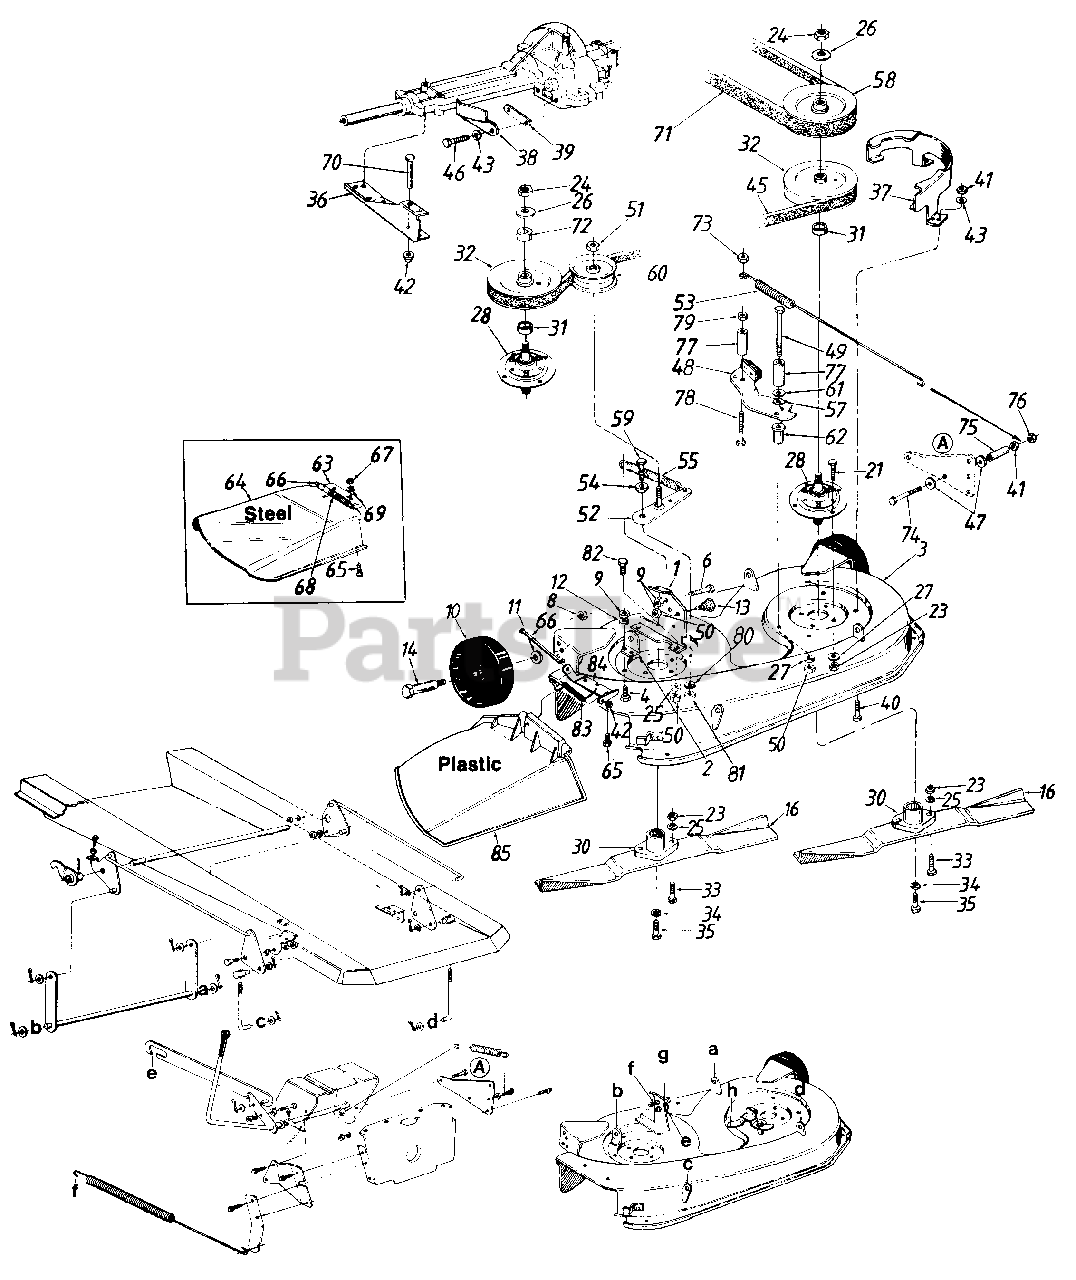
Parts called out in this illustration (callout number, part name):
1	Deck Disengagement Brkt.
2	Rear Deck Brkt.-R.H.
3	38" Deck Ass'y.
4	Hex Bolt 1/4-20 x .62" Lg.
6	Hex Wash. Hd. Scr. 1/4-20 x 1.5" Lg.
8	Hex L-Nut 3/8-16 Thd.
9	Hex Nut 1/4-20 Thd.
10	Deck Wheel
11	Bell-Wash. .380 I.D. x .88
12	L-Wash. 1/4 I.D.
13	Shld. Bolt .500 Dia. x .215" Lg.
14	Shld Bolt .498 Dia. x 1.53" Lg.
16	High Lift Blade
21	Hex Bolt 5/16-24 x .75" Lg.
23	Hex Nut 5/16-24 Thd.
24	Hex Jam Nut 5/8-18 Thd.
25	L-Wash. 5/16" I.D.
26	L-Wash. 5/8" I.D.*
27	Bell-Wash. .345 I.D. x .88
28	Blade Spindle Ass'y. Comp.
30	Blade Adapter
32	5" Dia. Pulley (1" Hub)
33	Hex Bolt 5/16-24 x 1.0" Lg. (Special)
34	L-Wash. 3/8" I.D. H.D.
35	Hex Bolt 3/8-24 x 1.0" Lg.
39	Belt Guard Spacer
40	Hex Bolt 1/4-20 x .62" Lg.
41	Hex Nut 1/4-20 Thd.
42	Speed Nut 1/4" Rod
43	L-Wash. 1/4" I.D.
45	V-Belt
46	Hex Bolt 1/4-20 x .85" Lg.
47	Fl-Wash. 1/4" I.D.
48	Deck Brake Brkt. Ass'y.
49	Hex Bolt 5/16-18 x 3.25" Lg.*
50	Hex Nut 5/16-18 Thd.*
51	Hex L-Nut 3/8-24 Thd.
52	Idler Brkt. Ass'y.
53	Extension Spring 17.75" Lg.
54	Shoulder Spacer
55	Extension Spring 73/4" Lg.
57	Wave Washer
58	5" Dia. Pulley (3/4" Hub)
59	Hex Bolt 3/8-16 x 1" Lg.*
60	Flat Idler Pulley
61	Shld. Spacer .27" Lg.
62	Spacer 1.46" Lg.
63	Chute Brkt. (Steel)
64	Chute Deflector (Steel)
65	Truss-Mach. Scr. 1/4-20 x .75" Lg.
66	Hinge Pin
67	Hex Nut 1/4-20 Thd.*
68	Torsion Spring 1.14" Lg.
69	Bell-Wash. 1/4" I.D.
71	V-Belt
73	Hex L-Nut 1/4-28 Thd.
74	Hex Bolt 1/4-20 x 2.5" Lg.*
75	Spacer 1/4" I.D. x 318" O.D.
76	Hex L-Nut 1/4-20 Thd.
77	Spacer 5/16" I.D. x 1/2" O.D.
78	Hex Bolt 1/4-28 x 1.75" Lg.*
79	Hex Nut 1/4-28 Thd.*
80	L-Wash. 3/8" I.D.*
81	Hex Nut 3/8-16 Thd.*
82	Hex Bolt 5/16-18 x .75" Lg.*
83	Torsion Spring
84	Hinge Mtg. Brkt.
85	Chute Ass'y. Comp. (Plastic)
